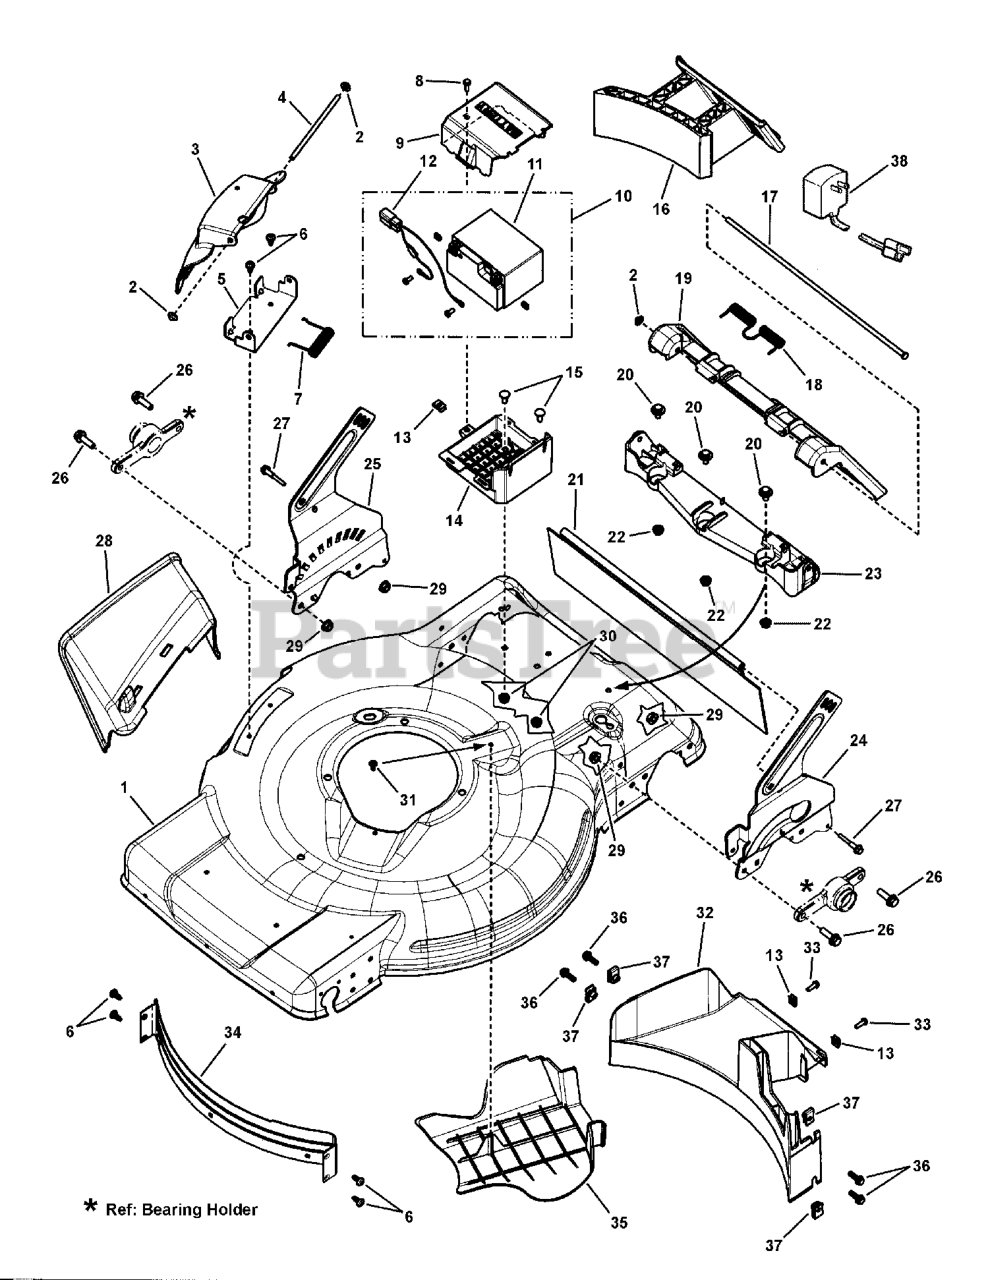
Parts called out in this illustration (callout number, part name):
1	DECK, 22", RWD, ES, DEERE
2	PUSHNUT, 1/4
3	COVER, MULCHING
4	ROD, PIVOT
5	BRACKET, CHUTE
6	TORX ST, 1/4-20 X .550
7	SPRING, TORSION, CHUTE
8	SCREW, HWFST,10C X 5/8
9	TOP, BATTERY BOX, WBM
10	ASSY, BATTERY W/HARNESS
11	SEALED LEAD ACID BATTERY, 12V
12	HARNESS, BATTERY
13	NUT, RETAINER SPEED #10C W/EXT
14	BOTTOM, BATTERY BOX, WBM
15	BOLT, FHSNB,1/4-20X5/8
16	PLUG, MULCHING, 22" DECK
17	ROD, PIVOT, REAR DOOR
18	SPRING, TORSION, REAR DOOR
19	DOOR, REAR DISCHARGE
20	SCREW, HHSTS, 1/4-20 x 5/8"
21	GUARD, REAR 22"
22	NUT, HFLN, 1/4-20
23	REAR DISCHARGE DOOR HINGE
24	BRKT, REAR WHEEL, LH, QUICK ADJUST
25	BRKT, REAR WHEEL, RH, QUICK ADJUST
26	BOLT, HFLB, 5/16-18 X 1 YZ
27	BOLT, DRAG SHIELD, 1/4 - 20 X 1.5
28	CHUTE, SIDE DISCHARGE, WBM, 22"
29	NUT, FLANGE LOCK, 5/16-18 YZ
30	NUT, .25-20 HEX FLG WHIZLK
31	SCREW, ROUND WASHER HEAD TORX, HI-LO
32	REAR, BAFFLE REAR WHEEL DRIVE WBM
33	SCREW, HWFST, 10C X 5/8
34	BAFFLE, FRONT
35	COVER, BELT DRIVE, REAR
36	BOLT, HFLB,1/4-20X3/4
37	U-NUT, 1/4-20
38	CHARGER, Battery (120 Volt; 60 Hertz)
